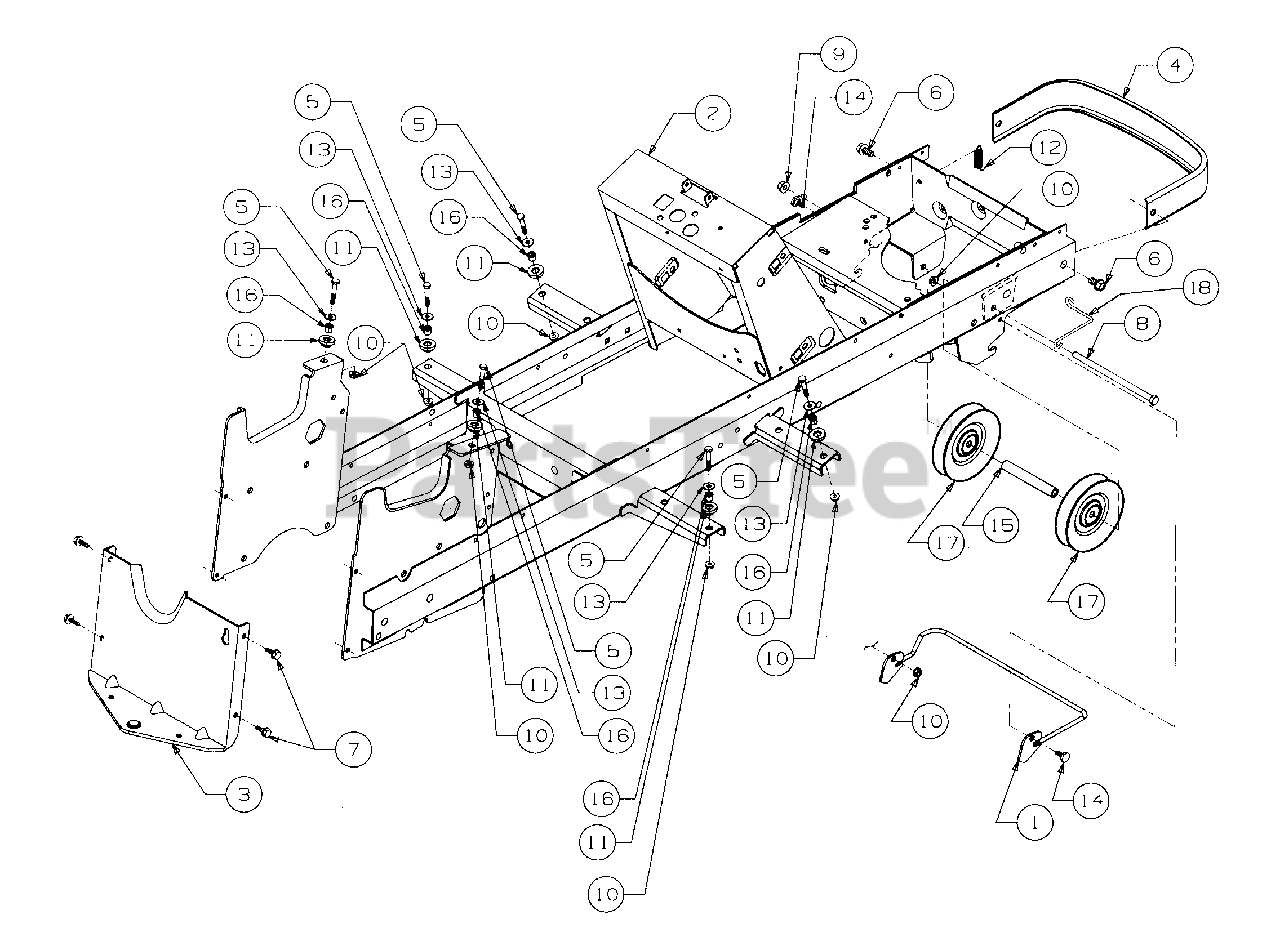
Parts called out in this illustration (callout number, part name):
1	Rod, Attach
2	Frame
3	Drawbar
4	Bumper
5	Screw, Hex Cap, 1/4-20 x 1.0
6	Screw, Hex Wsh Hd Tap 3/8-16 x .75
7	Screw, Hex Wsh Hd Tap 5/16-18 x .75
8	Screw, Hex Cap, 3/8-16 x 7.0
9	Nut, Hex Flanged Lock, 3/8-16
10	Nut, Hex Flange Lock, 1/4-20
11	Grommet, Insulator
12	Spring, Latch
13	Washer, Flat, .255 x .72 x .60
14	Bolt, Shoulder
15	Spacer, Idler, .407 x .62 x 4.38
16	Spacer, .28 x .40 x .42 Lg
17	Pulley, Idler
18	Belt Guide
